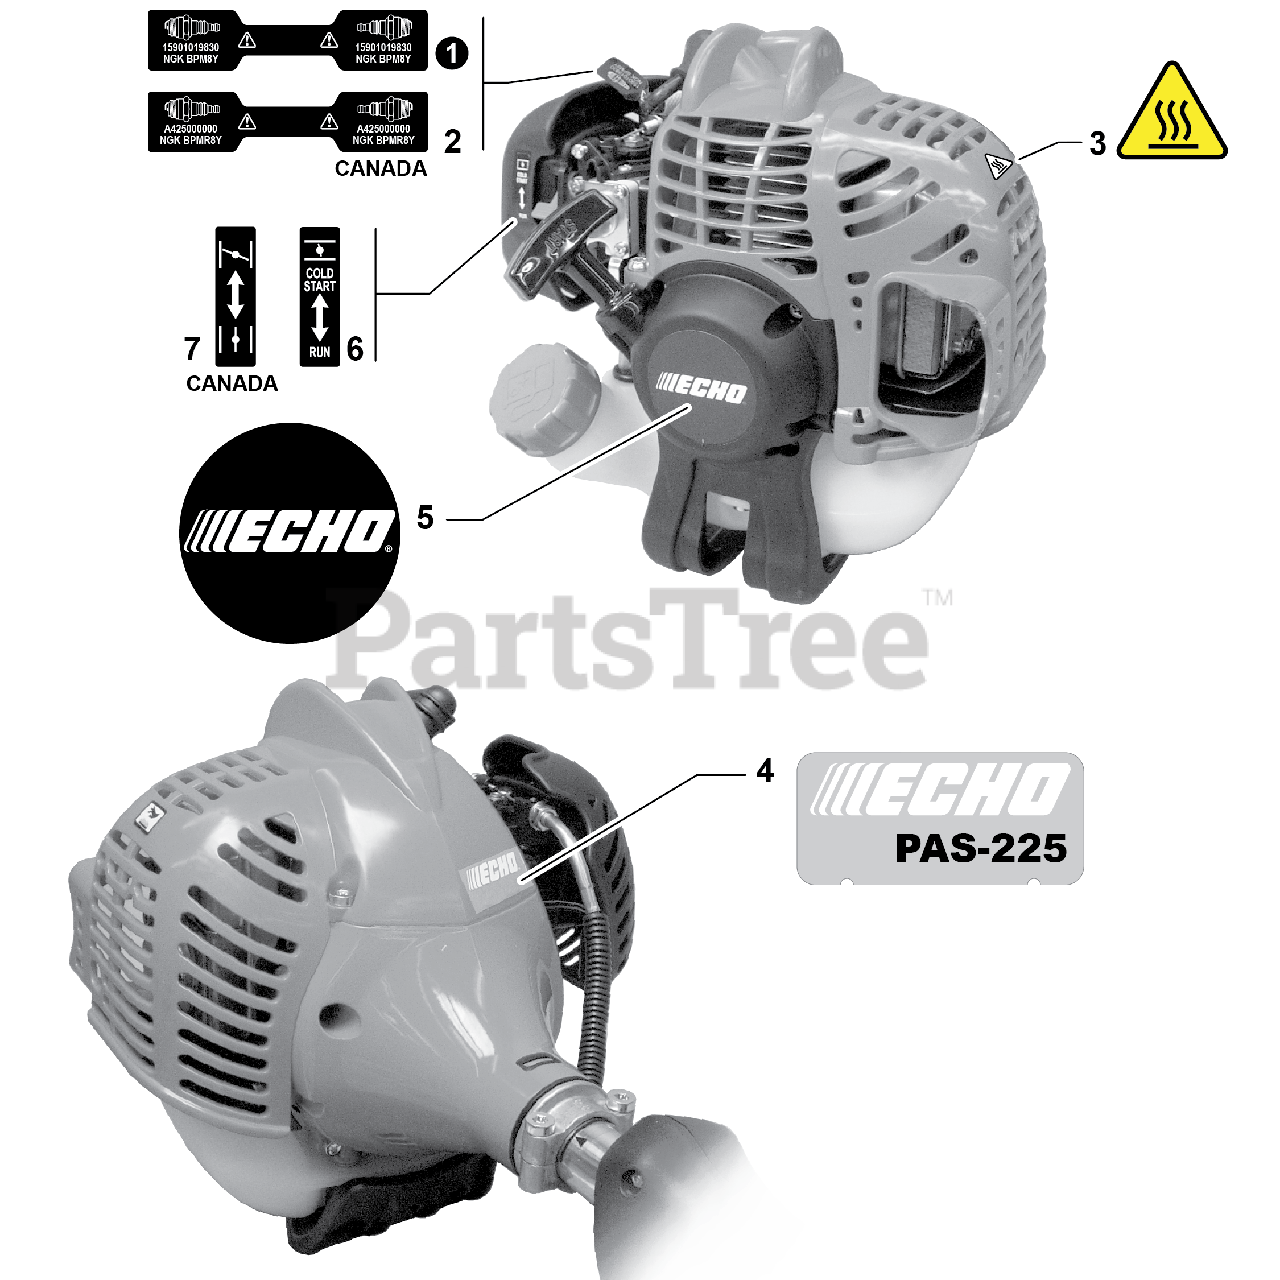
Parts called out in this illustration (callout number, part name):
1	LABEL, SPARK PLUG - BPM8Y
2	LABEL, SPARK PLUG - BPMR8Y
3	LABEL, CAUTION - HOT
4	LABEL, MODEL - PAS-225
5	LABEL, ECHO
6	LABEL, CHOKE
7	LABEL, CHOKE
